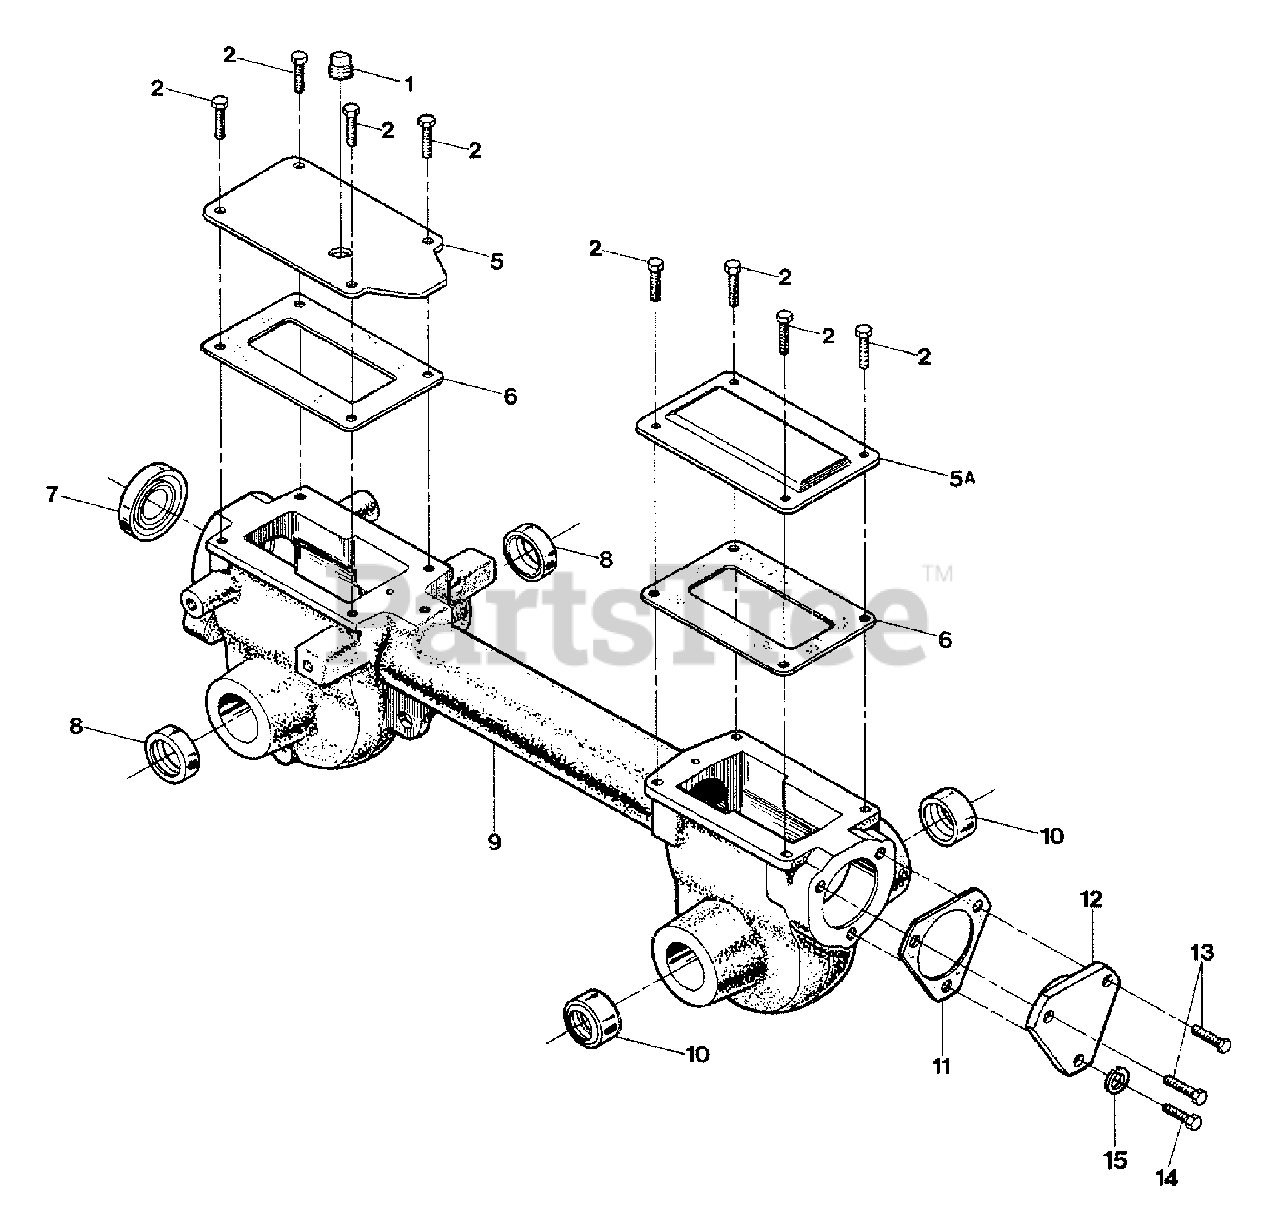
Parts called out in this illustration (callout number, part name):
1	Plug, Transmission Oil Fill
2	Flange Screw, 5/16-18 x 5/8, Grade 5
5	Front Cover, Transmission
5A	Rear Cover, Transmission
6	Gasket, Housing Cover
7	Oil Seal, Drive Shaft
8	Oil Seal, Wheel Shaft
9	Transmission Housing Assy
10	Oil Seal, Tine Shaft
11	Bearing Cap Gasket, .010" thick
12	Rear Bearing Cap
13	Flange Screw, 5/16-18 x 1
14	Flange Screw, 5/16-18 x 3/4
15	Lockwasher, 5/16
